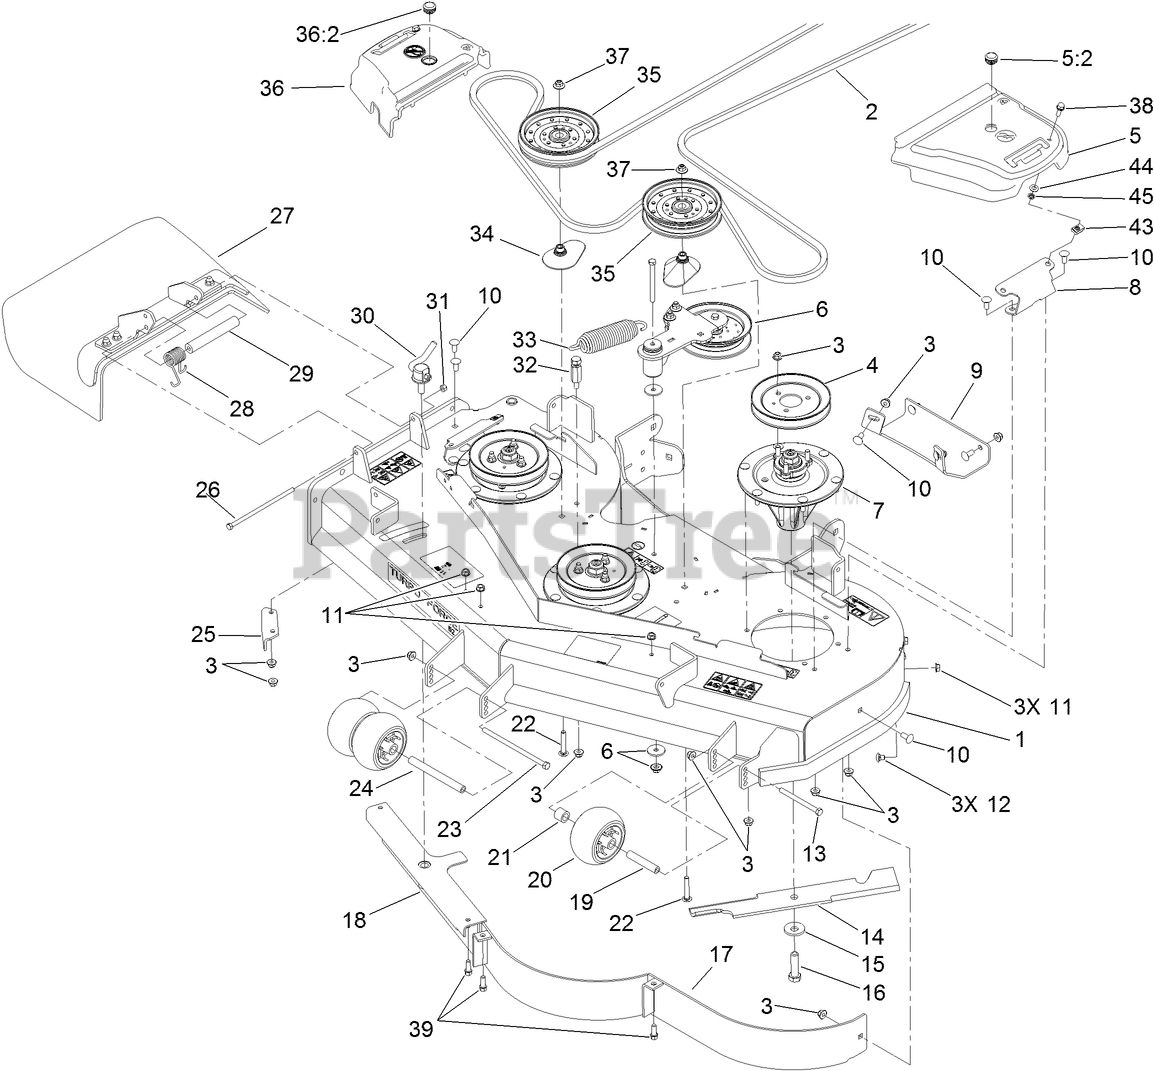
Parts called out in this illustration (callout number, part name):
1	DECK DECAL ASM
2	BELT-V
3	NUT-HF, NI
4	PULLEY
5	LH BELT COVER ASM
5:2	PLUG-PLASTIC
6	IDLER ARM ASM
7	SPINDLE ASM
8	BRACKET-COVER, BELT
9	PLATE-SKID
10	SCREW-CARR
11	NUT-HHF, WHIZ
12	SCREW-CARR
13	SCREW-HH
14	BLADE-18IN, HI FLOW
15	Washer-Blade Bolt, Heavy
16	SCREW-BLADE
17	BAFFLE ASM
18	BAFFLE
19	TUBE-SPANNER
20	ROLLER-SCALP, ANTI
21	TUBE-SPACER
22	BOLT-CARR, SHORT NECK
23	SCREW-HH
24	SPACER-WHEEL
25	BAFFLE-DISCHARGE
26	SCREW-HH
27	RUBBER DEFLECTOR ASM
28	SPRING-TORSION
29	SPACER
30	LEVER ASM
31	NUT-LOCK, NI
32	ANCHOR-SPRING, TALL
33	EXTENSION-SPRING
34	SPACER-PULLEY
35	PULLEY-IDLER, FLAT
36	RH BELT COVER ASM
36:2	PLUG-PLASTIC
37	NUT-FLANGE, NI
38	SCREW-HHF
39	SCREW-HWH
43	NUT-U
44	WASHER-THRUST
45	NUT-PUSH
